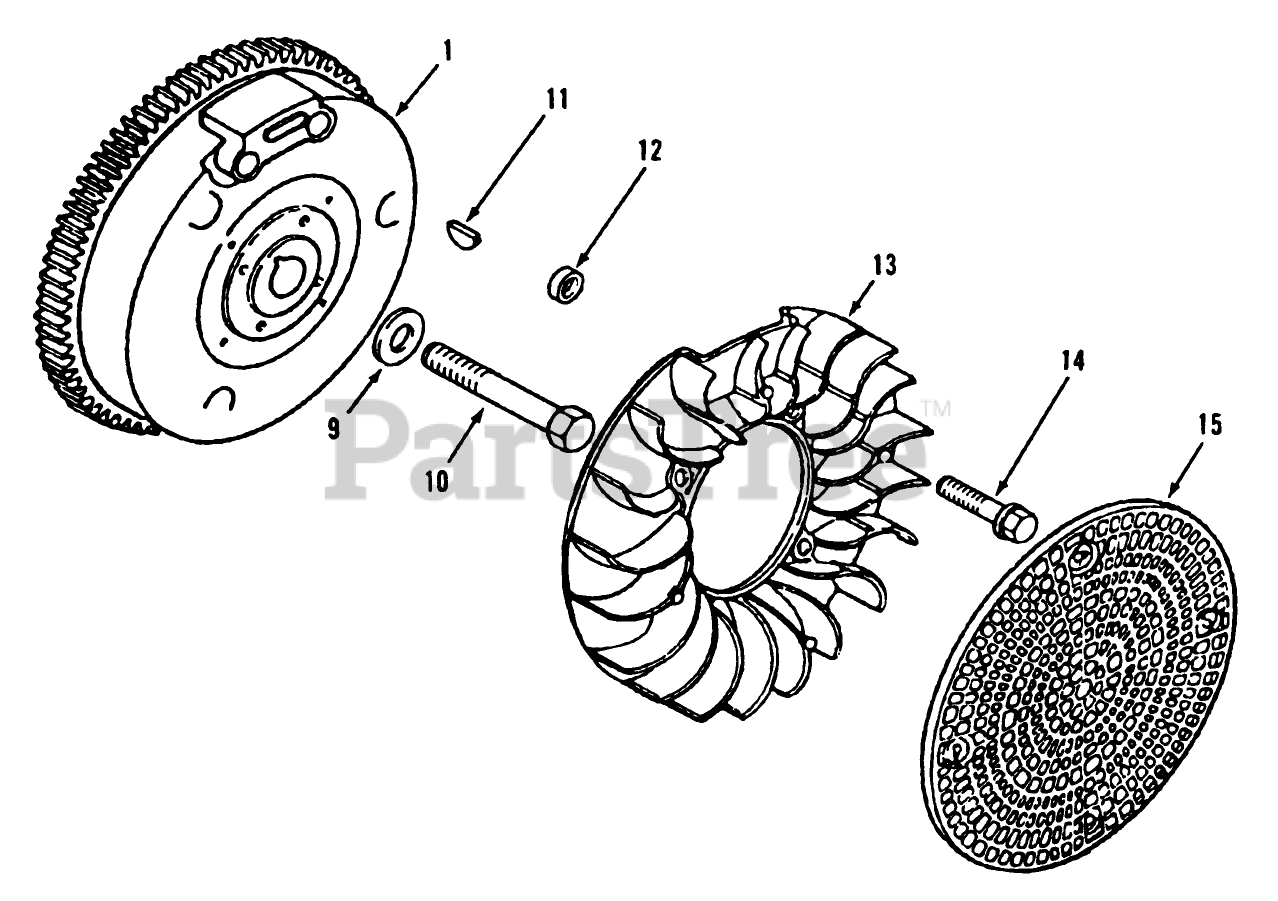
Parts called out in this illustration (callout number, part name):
1	KOHLER 47-025-53
9	KOHLER 52-468-15
10	KOHLER 25-086-24
11	KOHLER X-46-3
12	KOHLER 25-112-04
13	KOHLER 25-157-01
14	KOHLER 25-086-21
15	KOHLER 25-162-01
